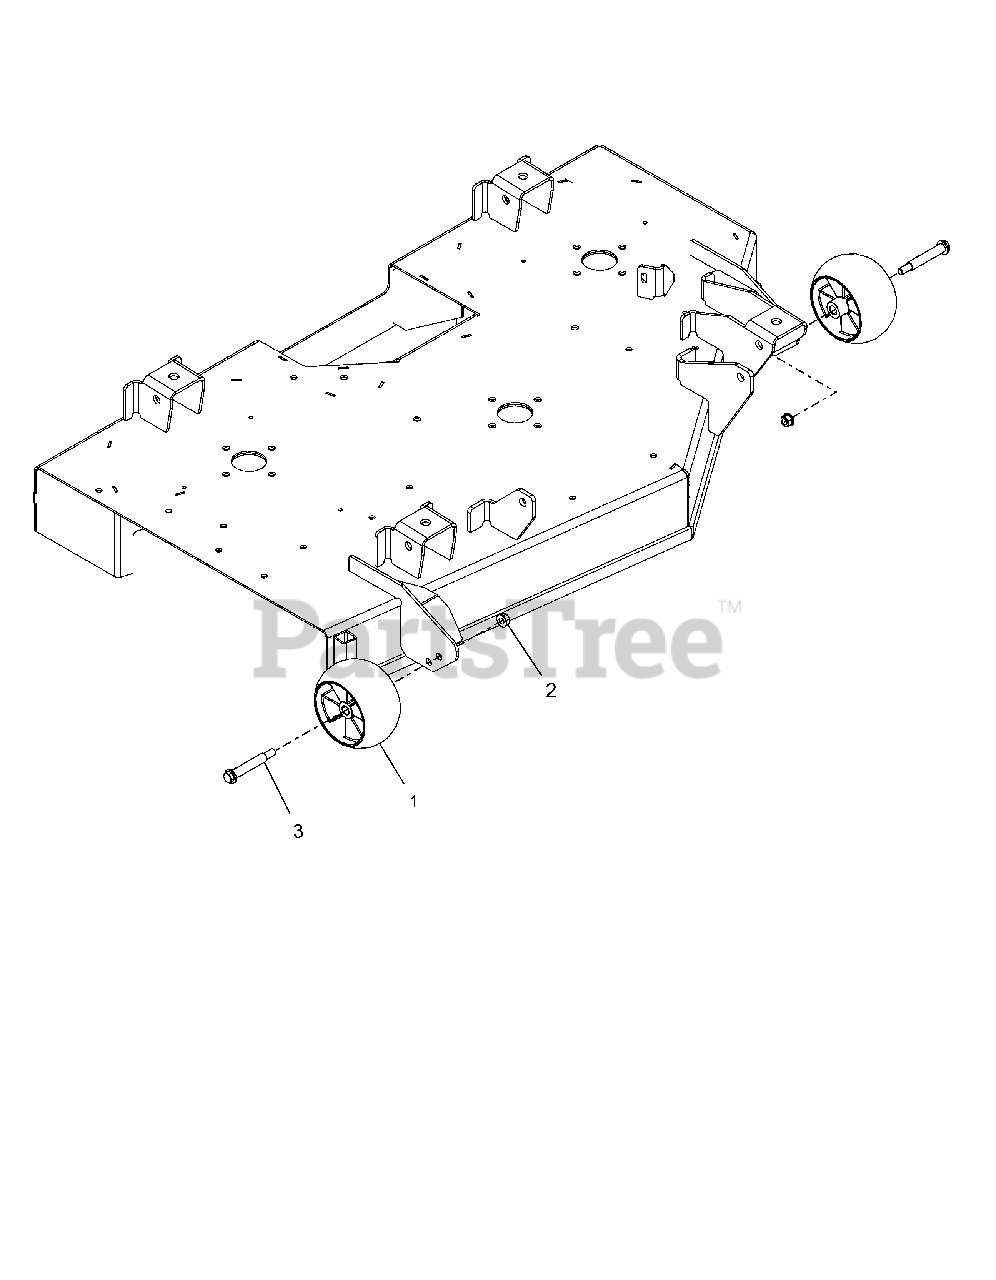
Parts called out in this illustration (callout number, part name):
1	ANTI-SCALP WHEEL - 5X OS
2	NUT-LK-TOP-FLG .38-16 ZC120
3	BLT-SHLDR .38-16X2.50 HWH G5
